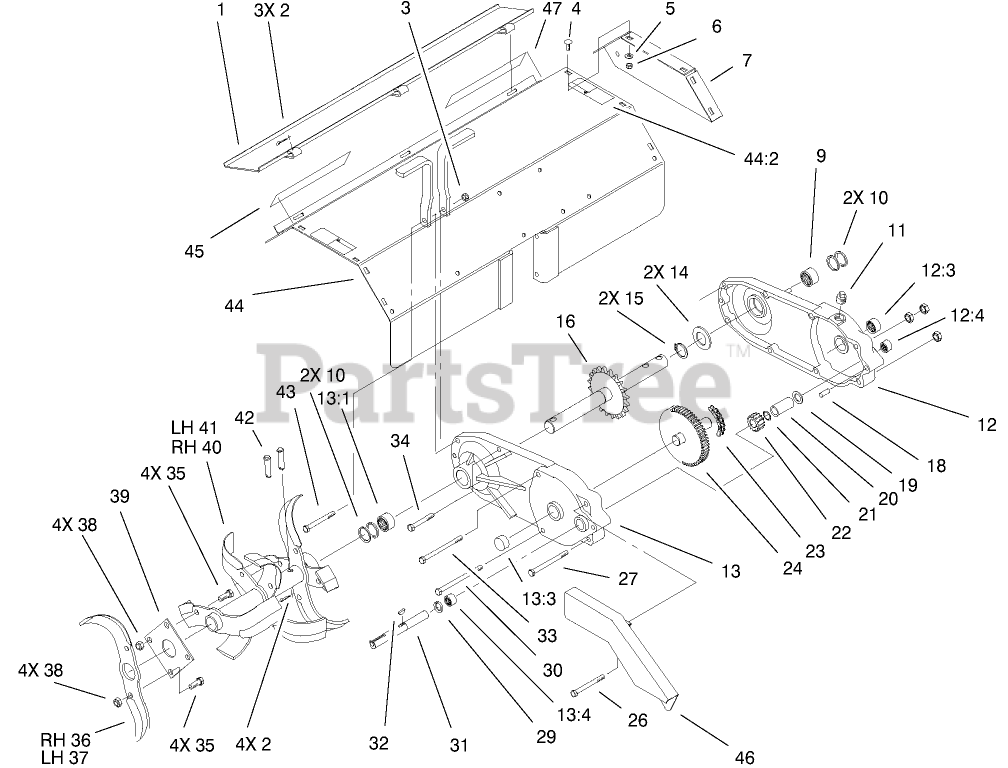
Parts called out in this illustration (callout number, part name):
1	GUARD ASM
2	PIN-COTTER
3	NUT-LOCK, NI
4	BOLT-CARR
5	WASHER-PLAIN
6	NUT-LOCK, NI
7	COVER-TINE END
11	PLUG-PIPE, SQH
12	Gear Case/Bearing ASM-RH
12:1	GEARCASE-TILLER
12:2	BEARING-NEEDLE
12:3	BEARING-NEEDLE
12:4	BEARING-NEEDLE
13	Gear Case/Bearing ASM-LH
13:1	GEARCASE-TILLER
13:2	BEARING-NEEDLE
13:3	BEARING-NEEDLE
13:4	BEARING-NEEDLE
14	WASHER
15	RING-RETAINING
16	TINE SHAFT ASM
18	PIN-ROLL
19	WASHER-THRUST
20	TUBE-SPACER
21	RING-SNAP
23	CHAIN
26	SCREW-HH
27	SCREW-HH
29	SEAL-OIL
30	SCREW-HH
31	SHAFT-INPUT
32	KEY-WOODRUFF
34	SCREW-HH
35	SCREW-HH
38	NUT-LOCK, NI
39	PLATE-TINE MOUNTING
40	RH TINE ASM
41	LH TINE ASM
42	PIN-CLEVIS
43	SCREW-HH
44	TINE SHIELD/DECAL ASM
44:2	DECAL-DANGER
46	GUARD-TILLER
